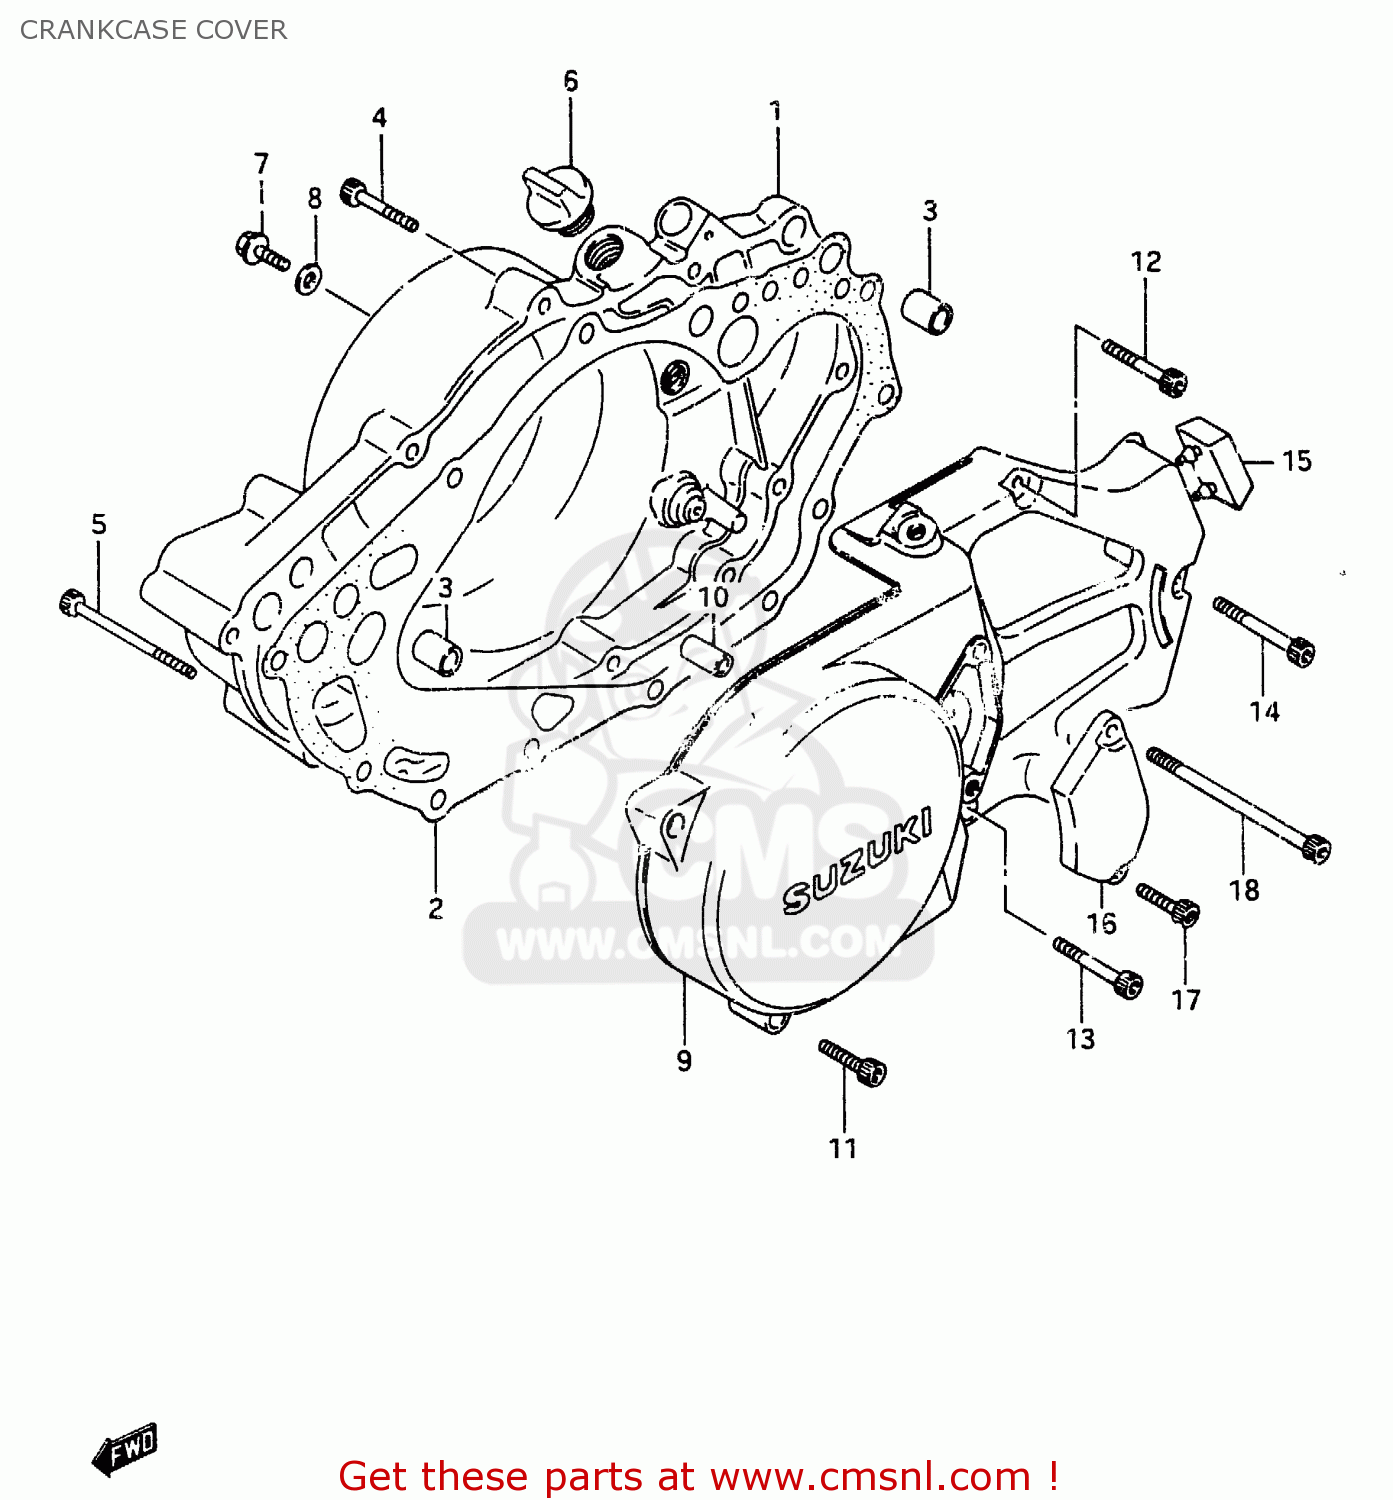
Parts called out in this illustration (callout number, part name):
1	COVER SET, CLUTCH
2	GASKET, CLUTCH COVER (MCA)
3	PIN
4	BOLT
5	BOLT (6X80)
6	PLUG SET
7	SCREW (6X10)
8	GASKET(6.2X11X1).2 (NAS)
9	COVER, MAGNETO
10	PIN
11	BOLT
12	BOLT
13	BOLT
14	BOLT
15	CUSHION
16	CAP, CLUTCH RELEASE ADJUSTER
17	BOLT
18	BOLT (6X85)
